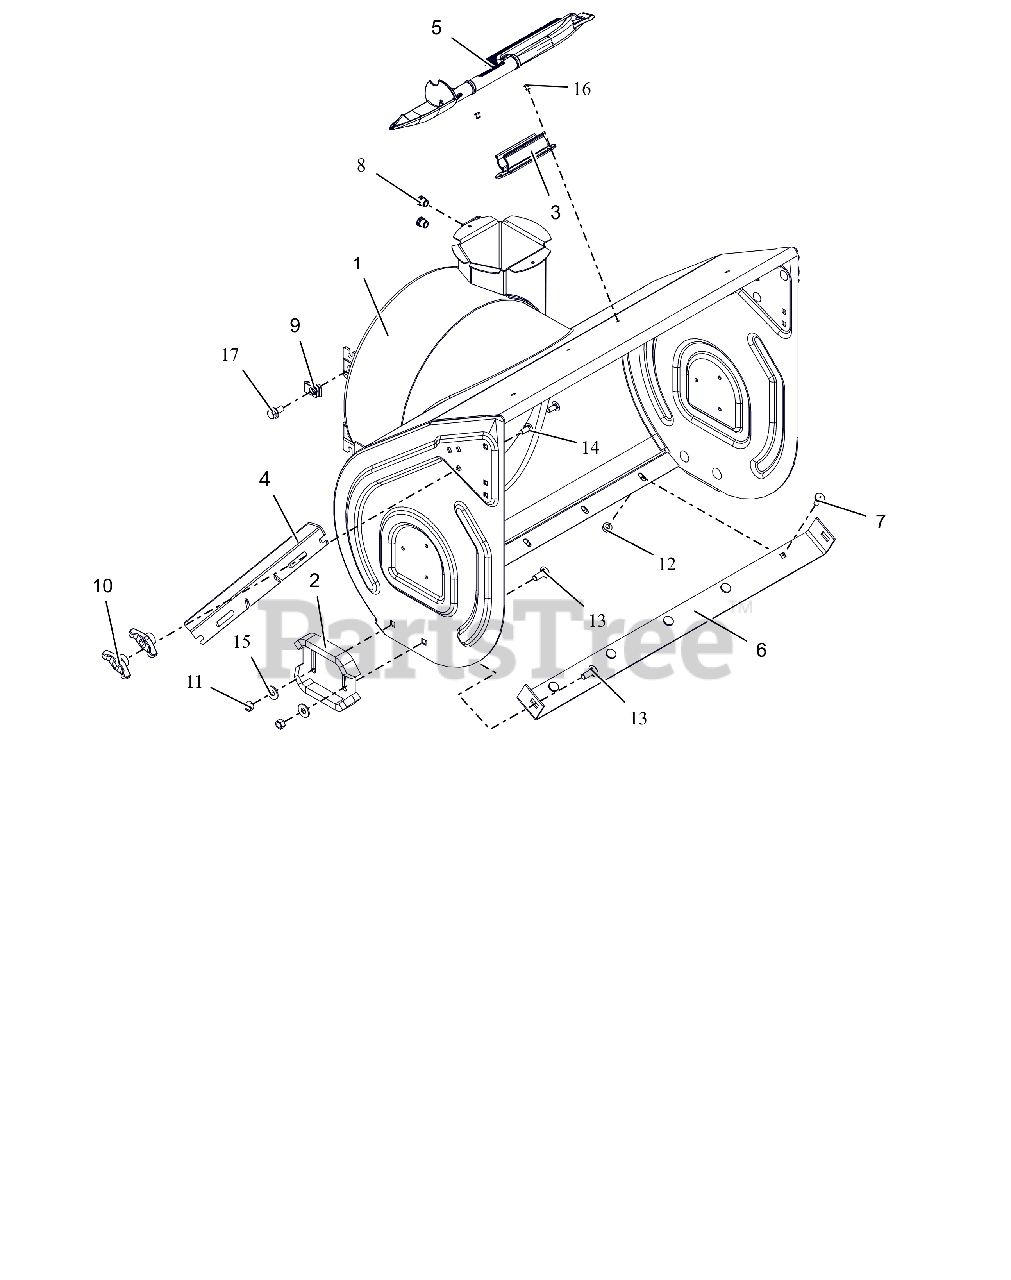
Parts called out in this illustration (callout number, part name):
1	BLOWER HOUSING W/DECAL 28"
2	RUNNER, SKID SHOE
3	MOUNT, SNOW CLEAN OUT
4	CUTTER, DRIFT
5	DEVICE, SNOW CLEAN OUT W/BRUSH
6	BLADE, SCRAPER-28"
7	BOLT, MODIFIED HEAD CARRIAGE
8	NUT,THD,INSERT .38-16 ZC120
9	NUT-RTNR .375-16X.37
10	KNOB,WING .31-18 UNC NYL/TALC
11	NUT-LK-CTR .38-16 ZC120
12	NUT-LK-TOP-FLG .312-18 GF ZCC
13	BLT,RHSSN .38-16X1.00 G5 ZCC
14	BLT, RHSSN.31-18X.750 G5 ZCC
15	WSHR,FLT .438X1.00X.083 ZCC
16	RVT, POP .1875 ZCC
